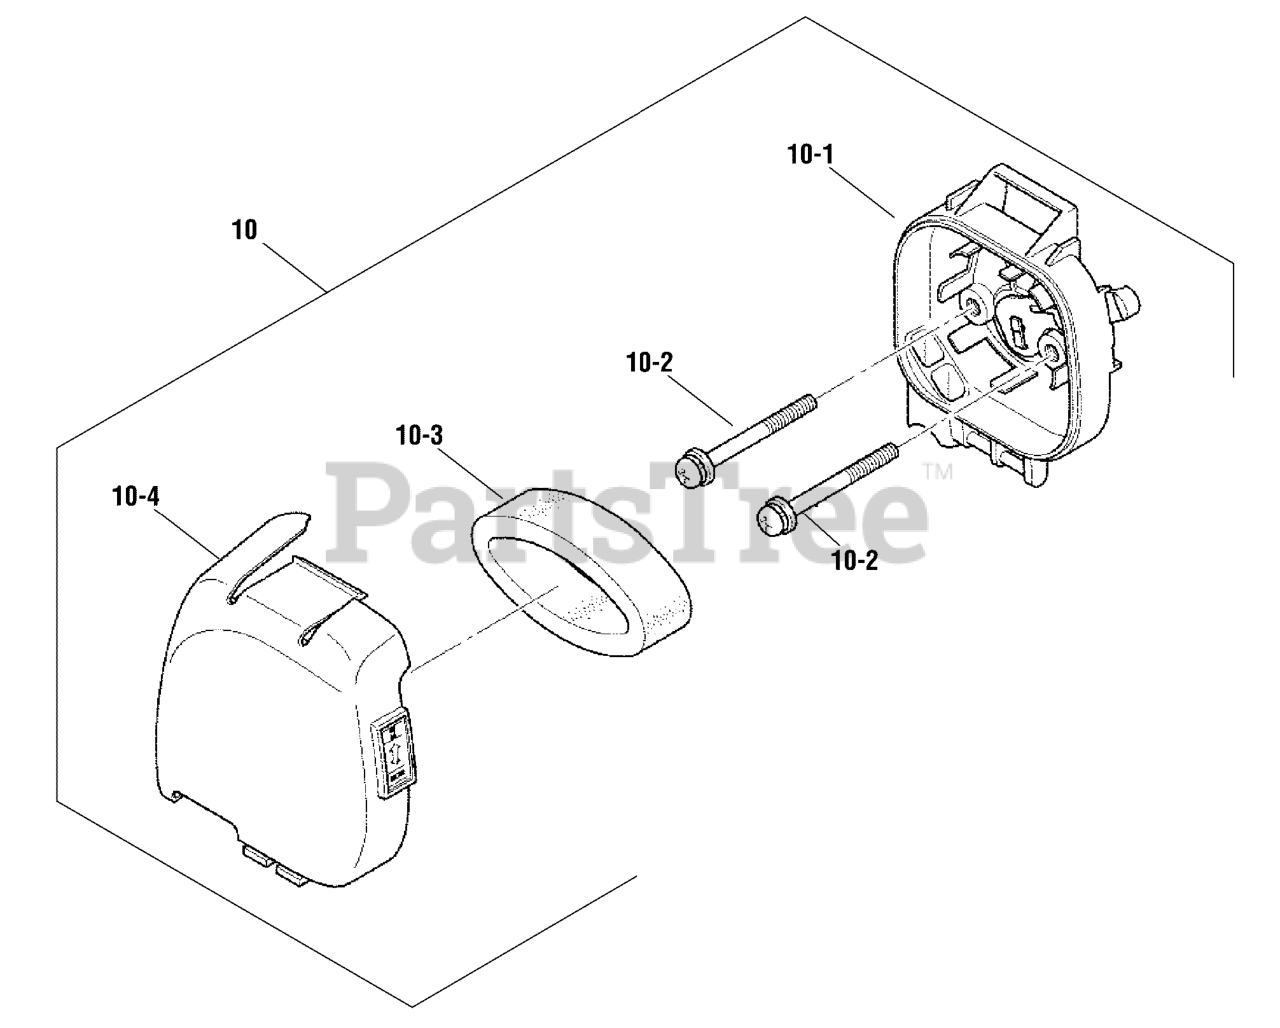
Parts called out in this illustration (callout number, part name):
10	AIR CLEANER ASSEMBLY
10-1	CASE, Cleaner
10-2	SCREW & WASHER
10-3	ELEMENT, Cleaner
10-4	COVER, Cleaner
